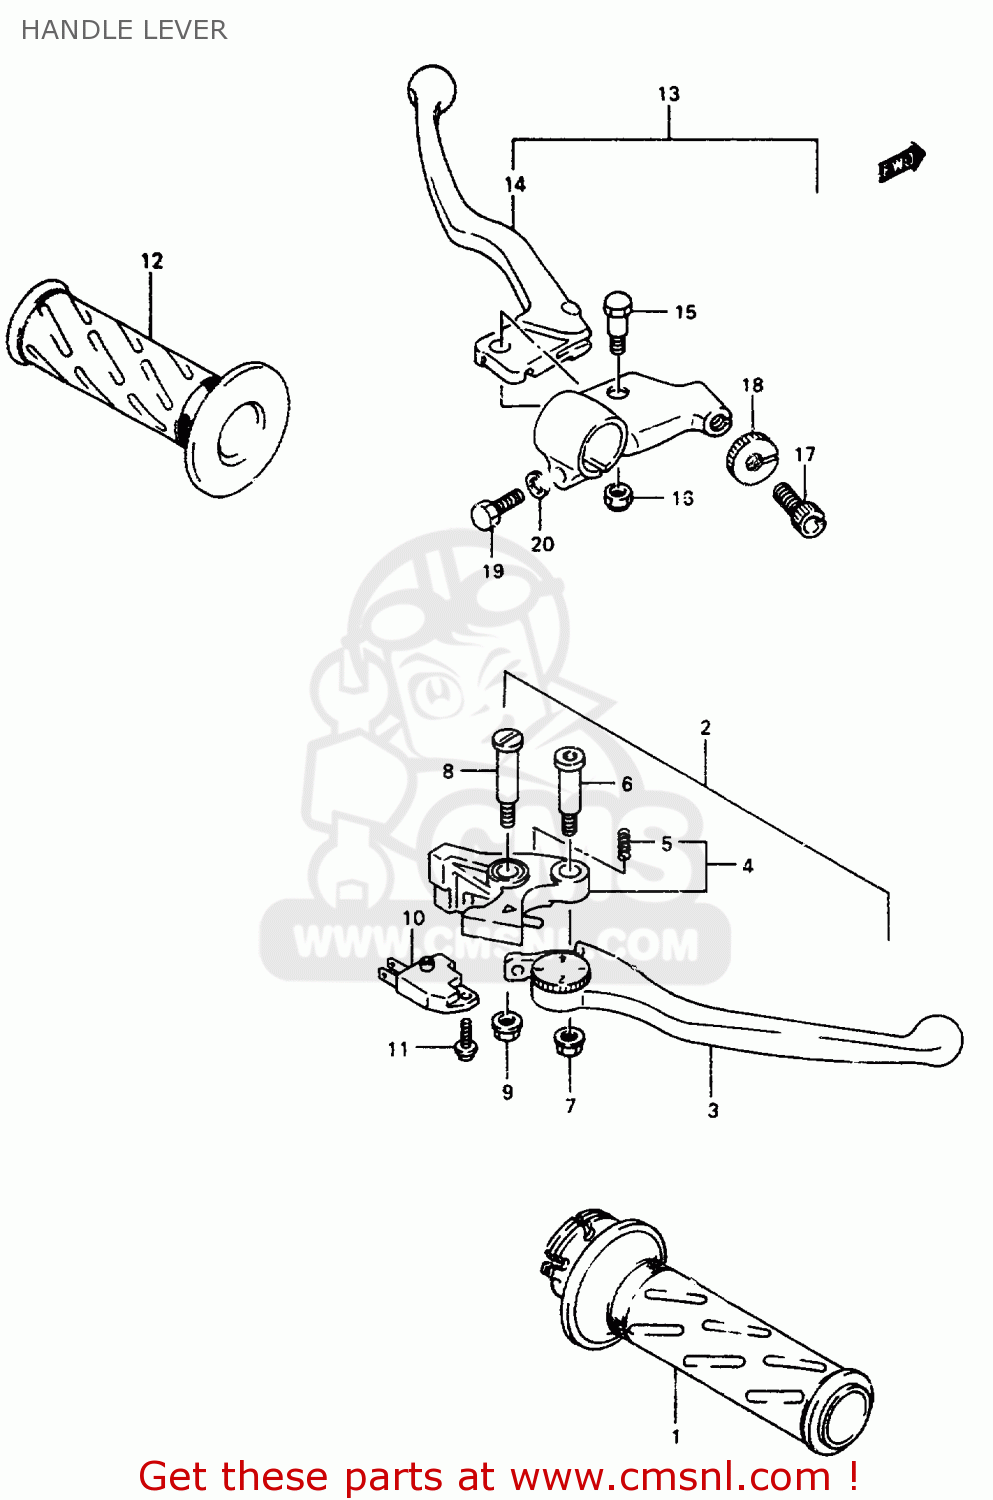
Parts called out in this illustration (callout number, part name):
1	GRIP,THROTTLE
2	LEVER ASSEMBLY,BRAKE
3	LEVER,ADJUST
4	KNOCKER
5	SPRING
6	BOLT,LEVER
7	NUT
8	BOLT,LEVER PIVOT
9	NUT
10	SWITCH ASSEMBLY,STOP
11	SCREW
12	GRIP,LEFT
13	LEVER ASSY,CLUTCH
14	LEVER,CLUTCH
15	BOLT,LEVER PIVOT
16	NUT
17	ADJUSTER,CABLE
18	NUT,CABLE ADJUSTER LOCK
19	BOLT
20	WASHER
